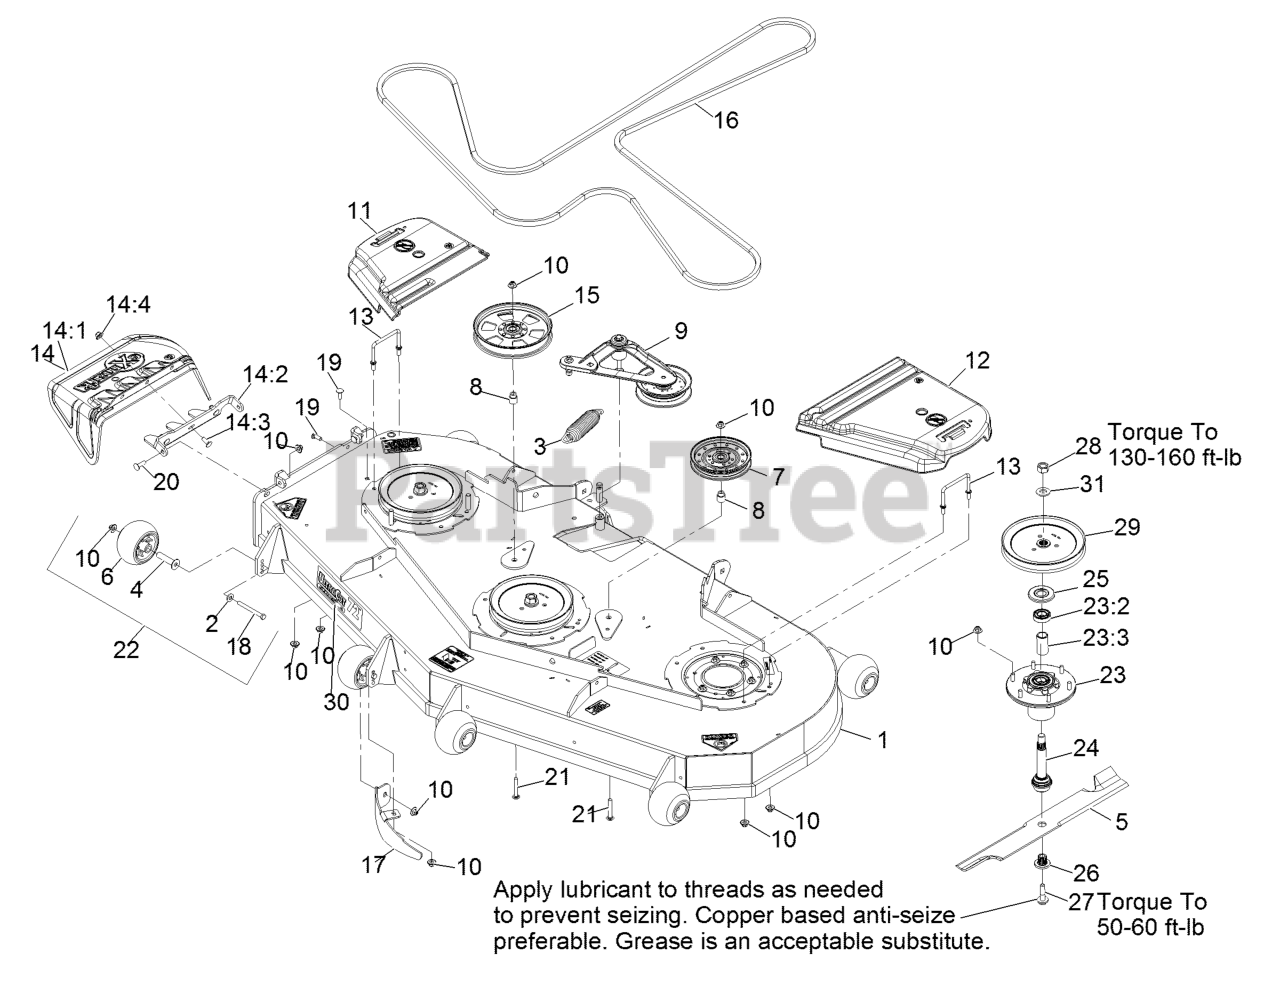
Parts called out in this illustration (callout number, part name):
1	ASM,DECK W/DECALS 724
2	WASHER-BELLEVILLE
3	SPRING-EXTENSION
4	AXLE, ROLLER
6	ROLLER-SCALP, ANTI
8	BUSHING-IDLER
9	DECK IDLER ASM
10	Nut-Nyloc 3/8-16 Flg
11	COVER-BELT, RH
12	COVER-BELT, LH
13	WIREFORM-COVER
14	ASM,DISCHARGE CHUTE
14:1	CHUTE,DISCHARGE
14:2	BRACKET,DISCHARGE CHUTE
14:3	SCREW-CARR
14:4	Nut-Nyloc 3/8-16 Flg
15	PULLEY-IDLER, FLAT
16	BELT-V
17	BAFFLE-DOGLEG, LZ72
18	SCREW-HH 3/8-16 X 3 3/4 GR 8
19	SCREW-CARR
20	Bolt-Carriage 3/8-16 X 1 1/4
21	SCREW-CARR
22	KIT, ANTI-SCALP ROLLER
23	ASM-CUTTER HSG WITH BEARINGS
23:2	BEARING-BALL
23:3	SPACER-BEARING
24	ASM-SPINDLE AND SEAL
25	GUARD,BEARING TOP .989
26	BUSHING,SPLINED
27	SCREW,SEMS 1/2-20 X 2.19
28	NUT-HEX
29	SHEAVE,BLADE DRIVE 8.74
30	DECAL,ULTRACUT 72 SERIES
